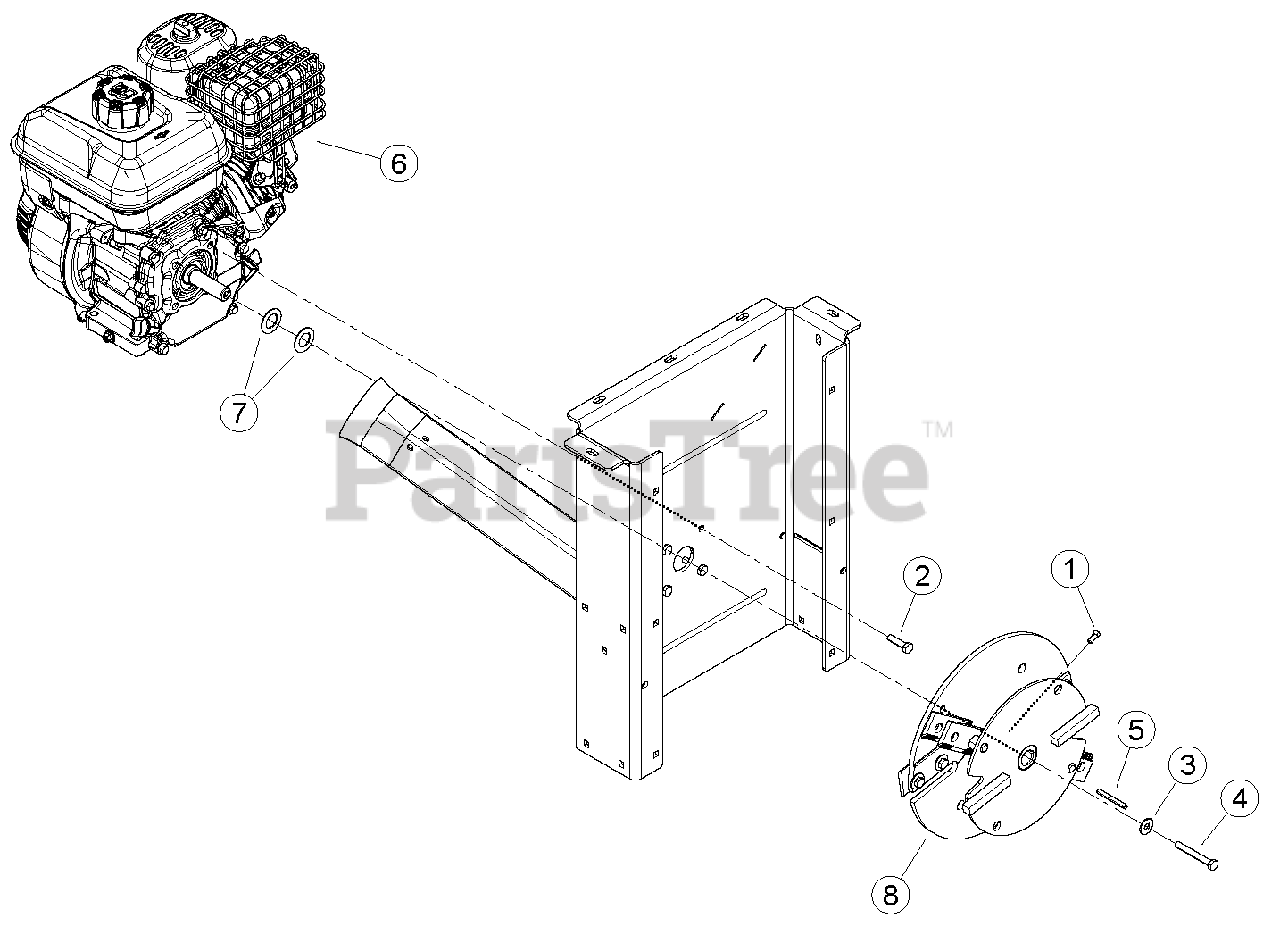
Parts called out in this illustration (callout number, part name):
1	SCREW, 1/4 X 1/2" SQ HD CP SET
2	BOLT, 5/16 X 1-1/4" HCS NF GR5 ZP
3	WASHER, 5/16 GR8 USS FLAT
4	BOLT, 5/16 X 2-1/2" NF GR5 ZP HHCS
5	KEY, 3/16 SQ X 2" PLAIN
6	ENGINE, 163CC 750 SERIES B&S (FOR SERVICE SEE ENGINE OWNER'S MANUAL OR YOUR NEAREST BRIGGS & STRATTON INDUSTRIAL ENGINE DEALER)
7	SPACER, ROTOR
8	ASSEMBLY, SC2170 ROTOR KNIVES
